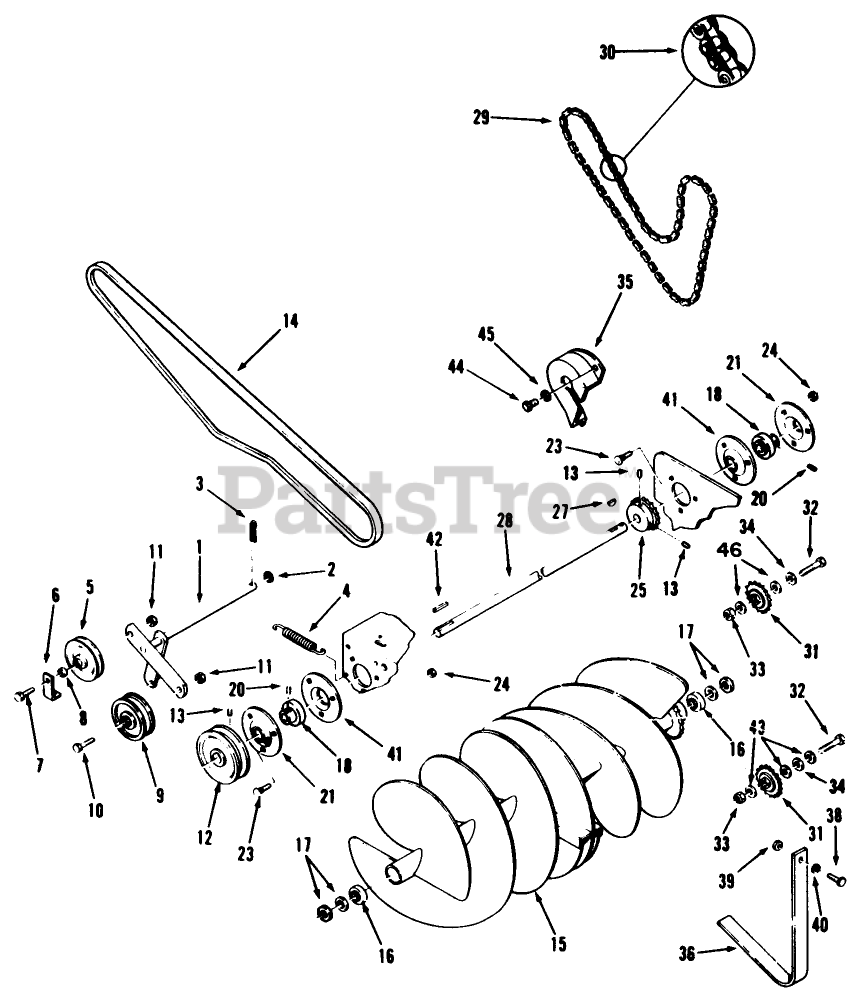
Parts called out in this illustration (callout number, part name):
4	SPRING-EXTENSION
7	SCREW-HH
8	SPACER
10	SCREW-HH
11	NUT-LOCK, NI
12	PULLEY
13	SCREW-SET, HSH
14	V-BELT
16	BEARING-BALL
18	BEARING AND COLLAR
20	SCREW-SET, HSH
21	FLANGE
23	BOLT-CARR
24	NUT-LOCK, NI
27	KEY-WOODRUFF
29	CHAIN
32	SCREW-HH
33	NUT-LOCK, NI
34	SPACER
35	GUARD-CHAIN
38	SCREW-HH
39	NUT-KEPS
40	WASHER-FLAT
41	FLANGE
43	WASHER-FLAT
44	Bolt
45	WASHER-FLAT
46	WASHER-FLAT
